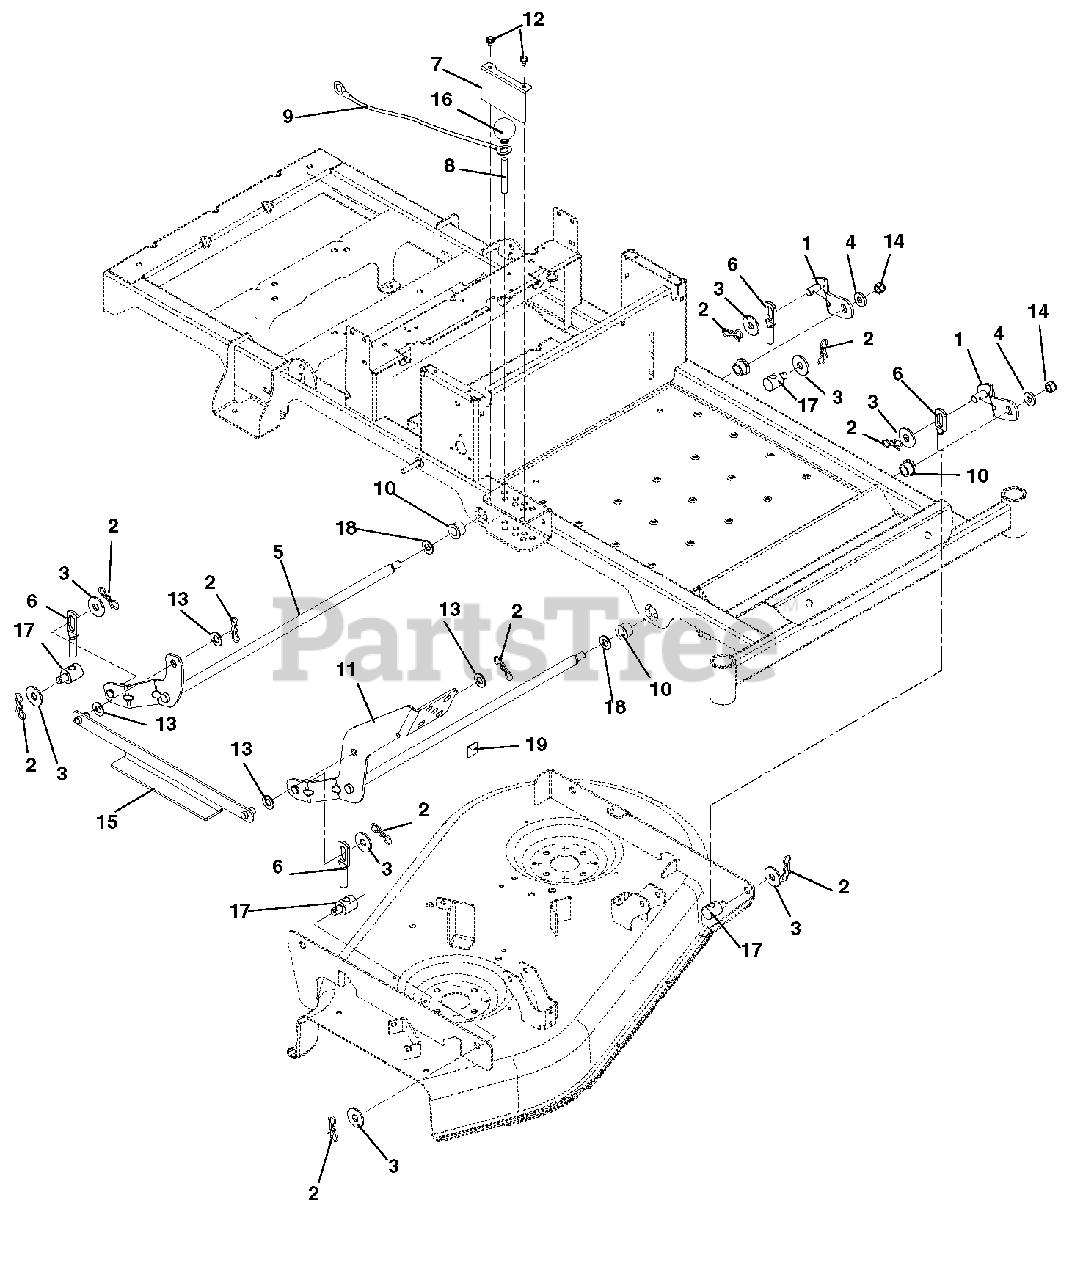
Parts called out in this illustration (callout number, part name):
1	Weldment, Lift Arm
2	Pin, Bow Tie Locking Cotter .091 x 1.875
3	Washer, Flat-STL.511 x 1.441 x .125
4	Washer, Flat-Steel .50 x 1.25 x .160
5	Weldment, Rear Deck Lift Shaft
6	Assembly, Deck Link
7	Guard, Deck Lift
8	Pin, Deck
9	Lanyard, Galvanized 12"
10	Bushing, Flange .627 x .879 x .469 x 1.120
11	Weldment, Deck Lift Pedal
12	Screw, Tap .25-20 x .37
13	Washer, Flat-Nylon .52 x 1.00 x .08
14	Nut, Nyloc 7/16-20
15	Weldment, Lift Link
16	Knob, Ball - Black 1.47" .375-16
17	Trunnion, .50
18	Washer, Flat Steel .656 x 1.31 x .095
19	Bumper, Rubber
